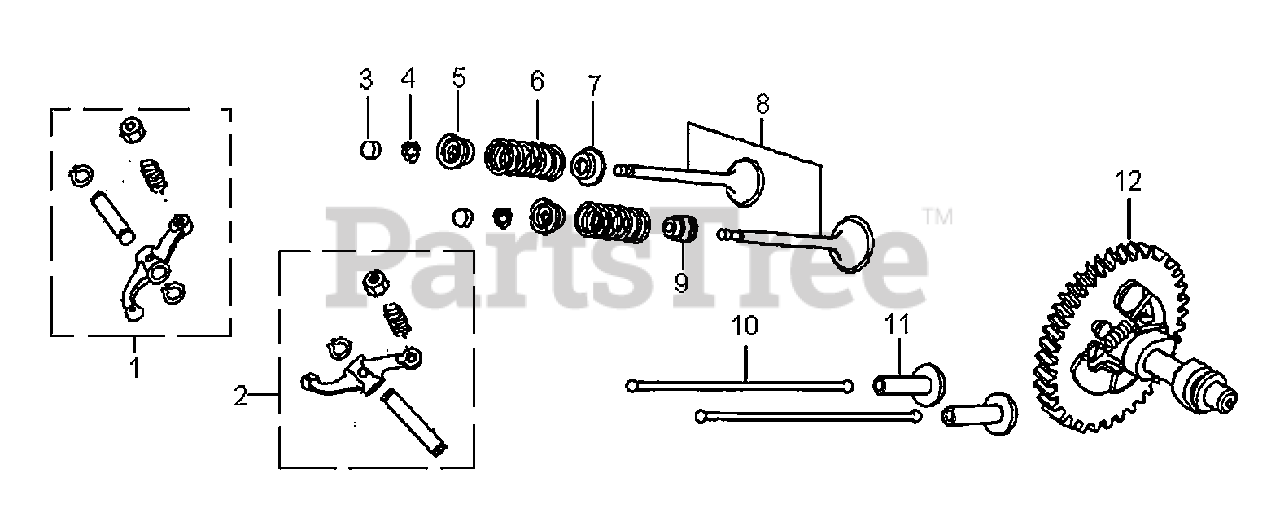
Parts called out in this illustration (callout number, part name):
1	ROCKER ARM ASSY.
2	ROCKER ARM ASSY.
3	ROTATOR,VALVE
4	VALVE LOCKER
5	RETAINER,VALVE SPRING
6	SPRING,VALVE
7	SEAT,VALVE SPRING
8	VALVE ASSY.
9	SEAL,VALVE STEM
11	LIFTER , VALVE
12	CAMSHAFT ASSY
